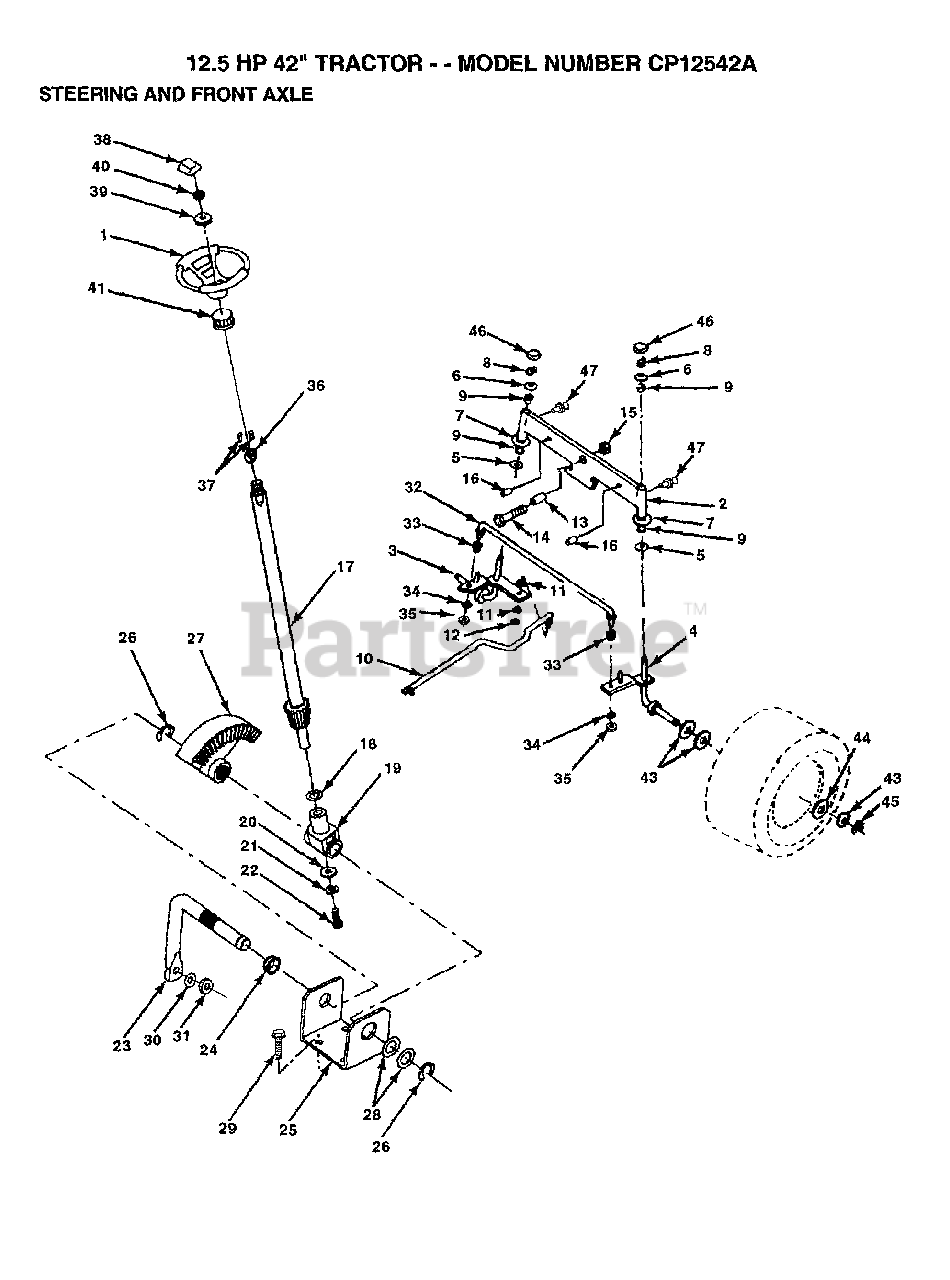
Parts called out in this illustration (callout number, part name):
3	SPINDLE LH
4	SPINDLE RH
5	WASHER .T
6	WASHER
7	WASHER
8	RING
9	COL. SRTG. BEAR.
11	LOCKWASHER
13	BEARING
14	BOLT HEX 5/8-11
16	AXLE PIN
17	STEERING SHAFT
18	THRUST WASHER
19	SUPPORT.SHAFT
21	LOCKWASHER
22	"SCREW,SPECIAL"
24	NYLINER T
25	"BRKT,STEERING"
26	RING
28	WASHER .T
29	SCREW
30	LOCKWASHER
32	TIE ROD
33	BUSHING.DRAGLINK
34	WASHER
35	COTTER PIN
38	ST WHL INSERT CAP
39	WASHER
41	ADAPTER LT
43	WASHER
44	WASHER
45	RING
46	CAP
47	ZERK M
